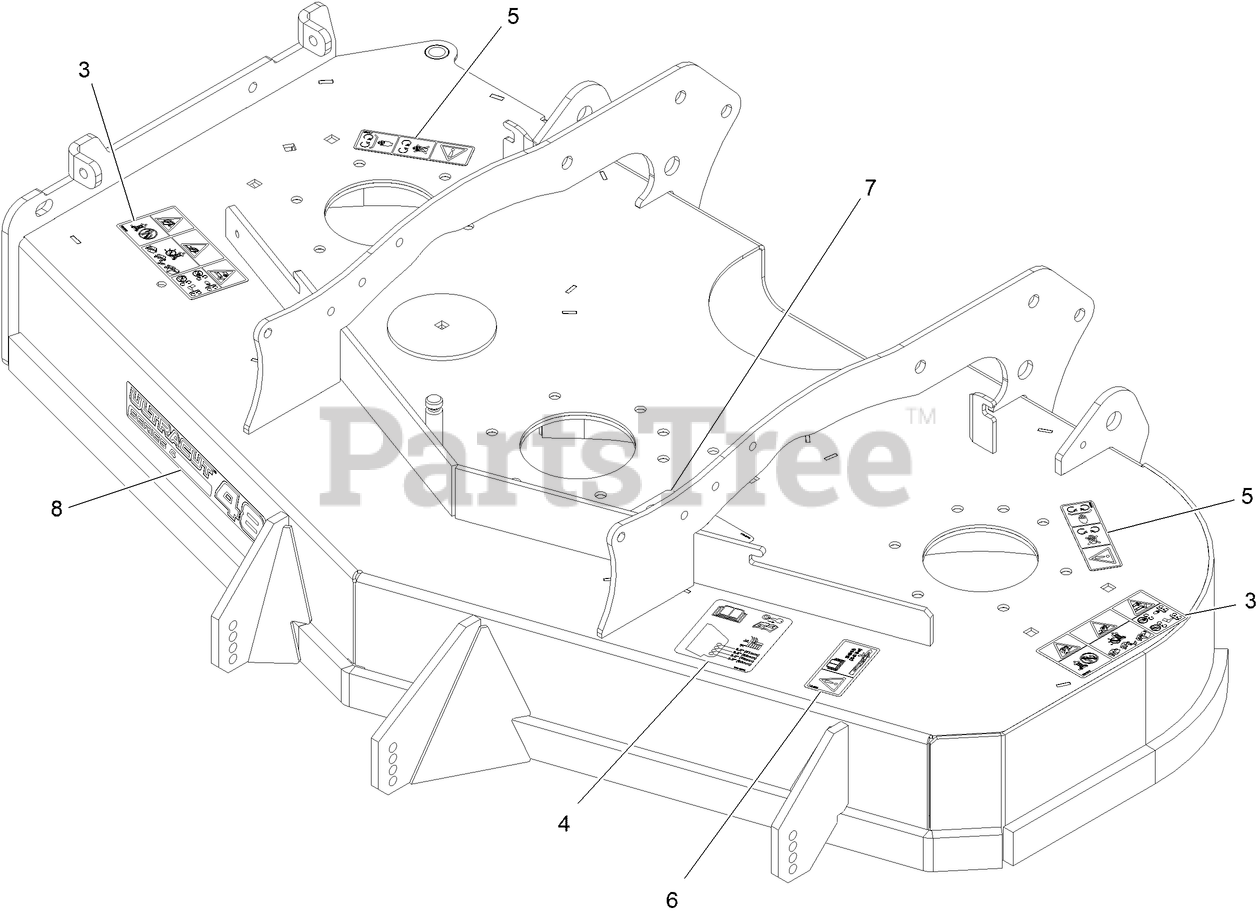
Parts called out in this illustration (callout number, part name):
3	DECAL-WARNING THROWN OBJ
4	DECAL-ROLLER, ANTI-SCALP
5	DECAL-COVER, MISSING
6	DECAL-TORQUE, BOLT
7	DECAL-BELT ROUTING
8	DECAL, 484
